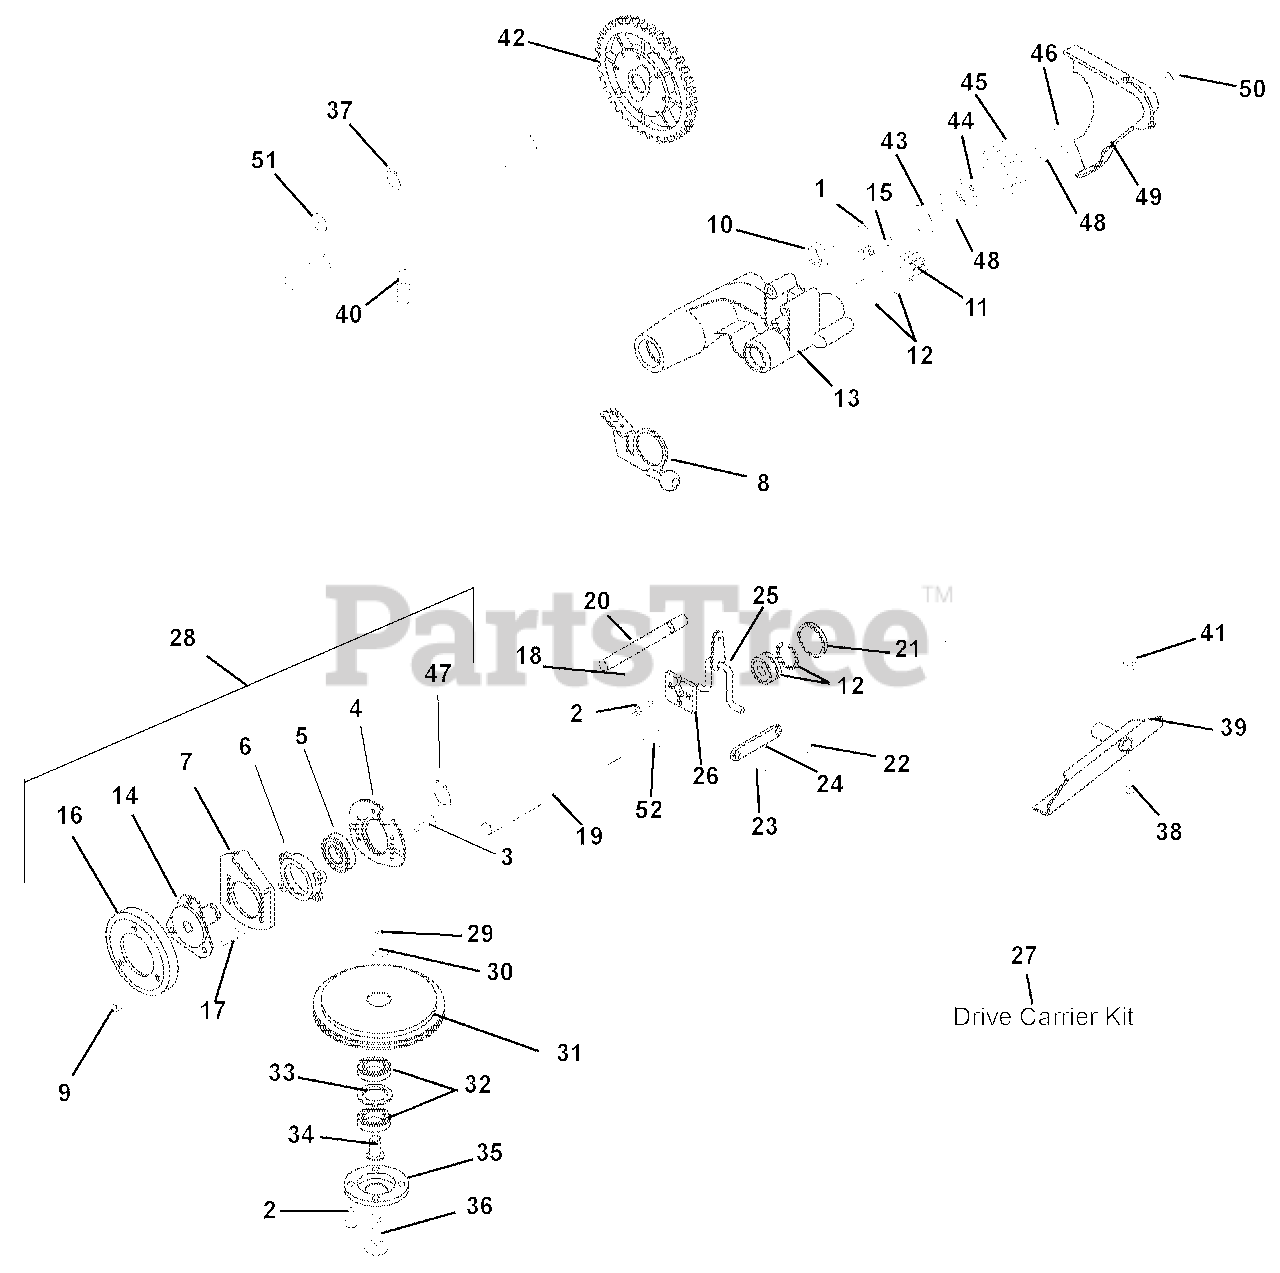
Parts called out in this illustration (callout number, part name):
1	Ring, Retaining External .438 x .035
2	Screw, Tapping 12-24 x .50 Hex Washer Head
3	Screw, Tapping 5 x 0.8 x 16MM
4	Bearing Retainer
5	Bearing Ball 1.00 x 2.00 x .56
6	Bearing Retainer
7	Bearing Plate
8	Drive Actuator Weldment
9	Nut, Locking Center .25-20
10	Bearing, Ball .625 x 1.38 x .44
11	Pinion, D-Shaft
12	Bearing, Ball .50 x 1.375 x .437
13	Drive Mount
14	Hub, Friction Wheel
15	Idler Shaft
16	Disc, Friction
17	Bolt, Hex .25-20 x .50 Grade 5
18	Pin, Roll .188 x .88
19	Shaft, Friction Disk
20	Rod, Guide
21	Washer, Flat Steel 1.390 x 2.00 x .020
22	Push Nut .25
23	Pin, Roll .125 x .50
24	Shift Link
25	Shift Arm Weldment
26	Retainer Plate
27	Kit, LM Drive Carrier (Includes Items 1 - 26)
28	Friction Wheel Assembly
29	Nut, Locking Center .31-18
30	Washer, Flat Steel .38 x .87 x .179
31	Friction Sheave
32	Bearing, Ball .625 x 1.375 x .43
33	Washer, Flat Steel 1.062 x 1.344 x .032
34	Spindle, Bearing
35	Bearing, Retainer
36	Bolt, Round Head Square Neck .31-18 x 1.75 Grade 5
37	Ring, Retaining External .579 x .930
38	Bolt, Round Head Square Short Neck .31-18 x .62
39	Pivot Channel Weldment
40	Spring, Tension .051 x .60 x 2.25
41	Nut, Locking-Top-Flange .31-18
42	Differential Assembly
43	Retainer
44	Bearing, Ball .50 x 1.38 x .437
45	Idler Gear
46	Washer, Flat Steel .531 x 1.00 x .063
47	Ring, Retaining External 1.00 x .042
48	Washer, Flat Steel .520 x .827 x .062
49	Gear Cover
50	Ring, Retaining External .438 x .035
51	Washer, Flat Steel .630 x 1.250 x .062
52	Washer, Flat Steel .505 x .880 x .072
